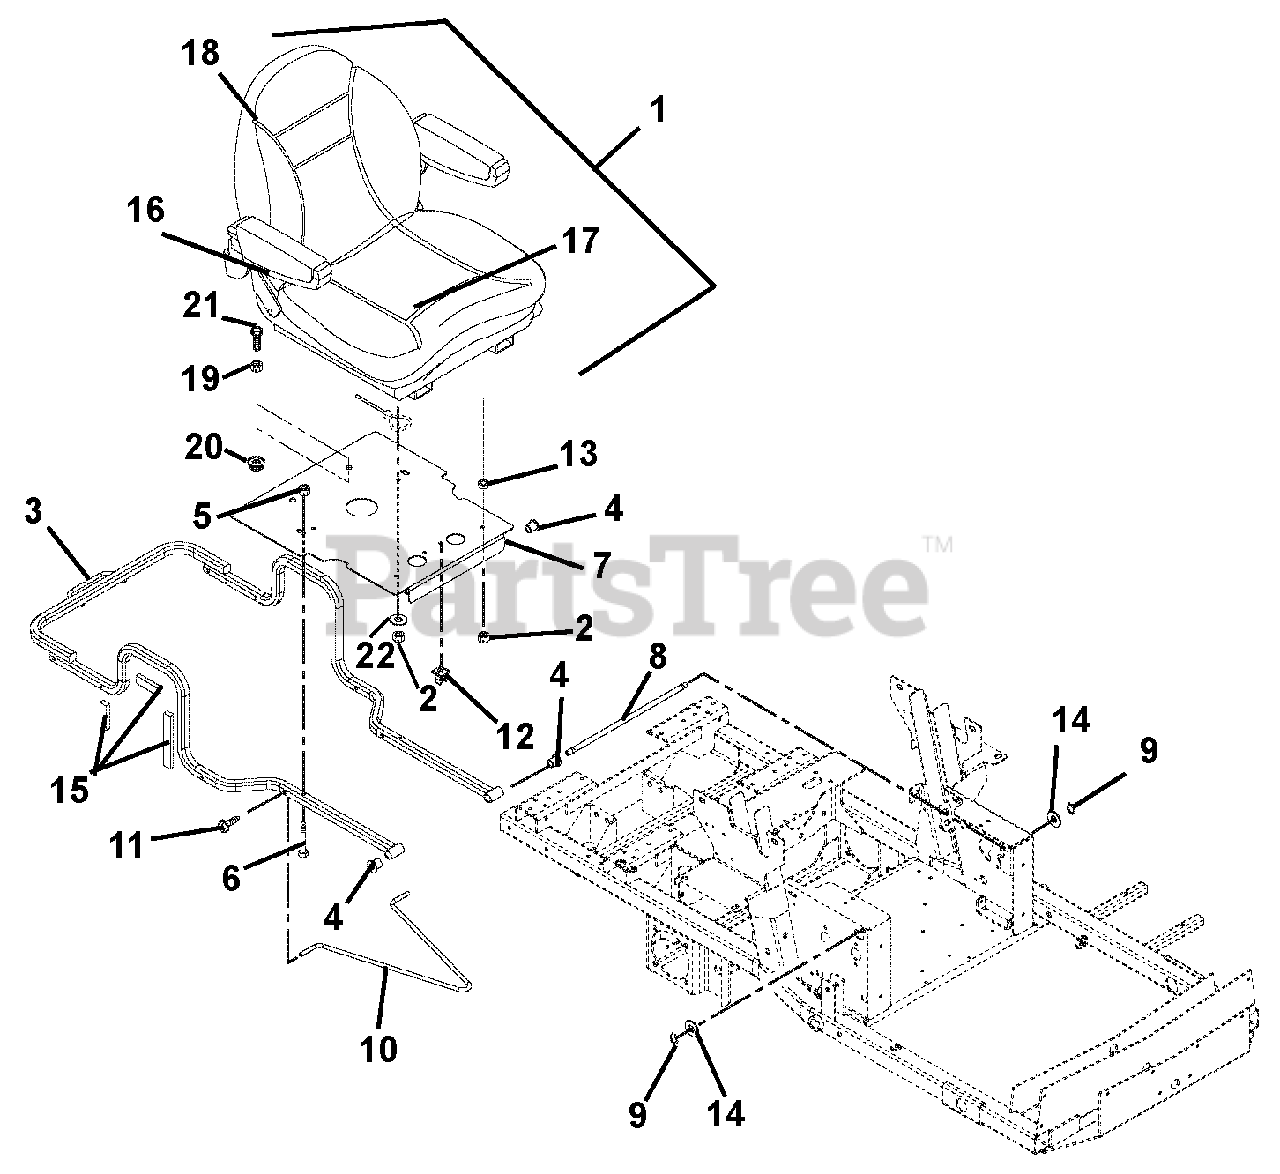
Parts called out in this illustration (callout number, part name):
1	Seat, Suspension
2	Nut, Locking Top Flange .31-18
3	Weldment, Hood Frame
4	Bushing, Flange .515 x .750 x .745 x 1.00
5	Nut, Locking Top Flange .38-16
6	Bolt, Rib Neck .38-16 x 1.50
7	Weldment, Seat Pivot Mount
8	Rod, Seat Frame Pivot
9	Ring, Retaining External .500 x .050
10	Rod, Prop
11	Screw, Tapping .25-20 x .50 Hex Washer Head
13	Bushing, Sleeve .377 x .624 x .235
14	Washer, Flat Steel .531 x 1.06 x .095
15	Tape, VHB
16	Kit, Arm Pad (1 per bag)
17	Kit, Seat Cushion
18	Kit, Back Cushion
19	Nut, Hex .50-13
20	Nut, Locking Top Flange .50-13
21	Bolt, Hex .50-13 x 1.50
22	Washer, Flat Steel .328 x 1.00 x .094
